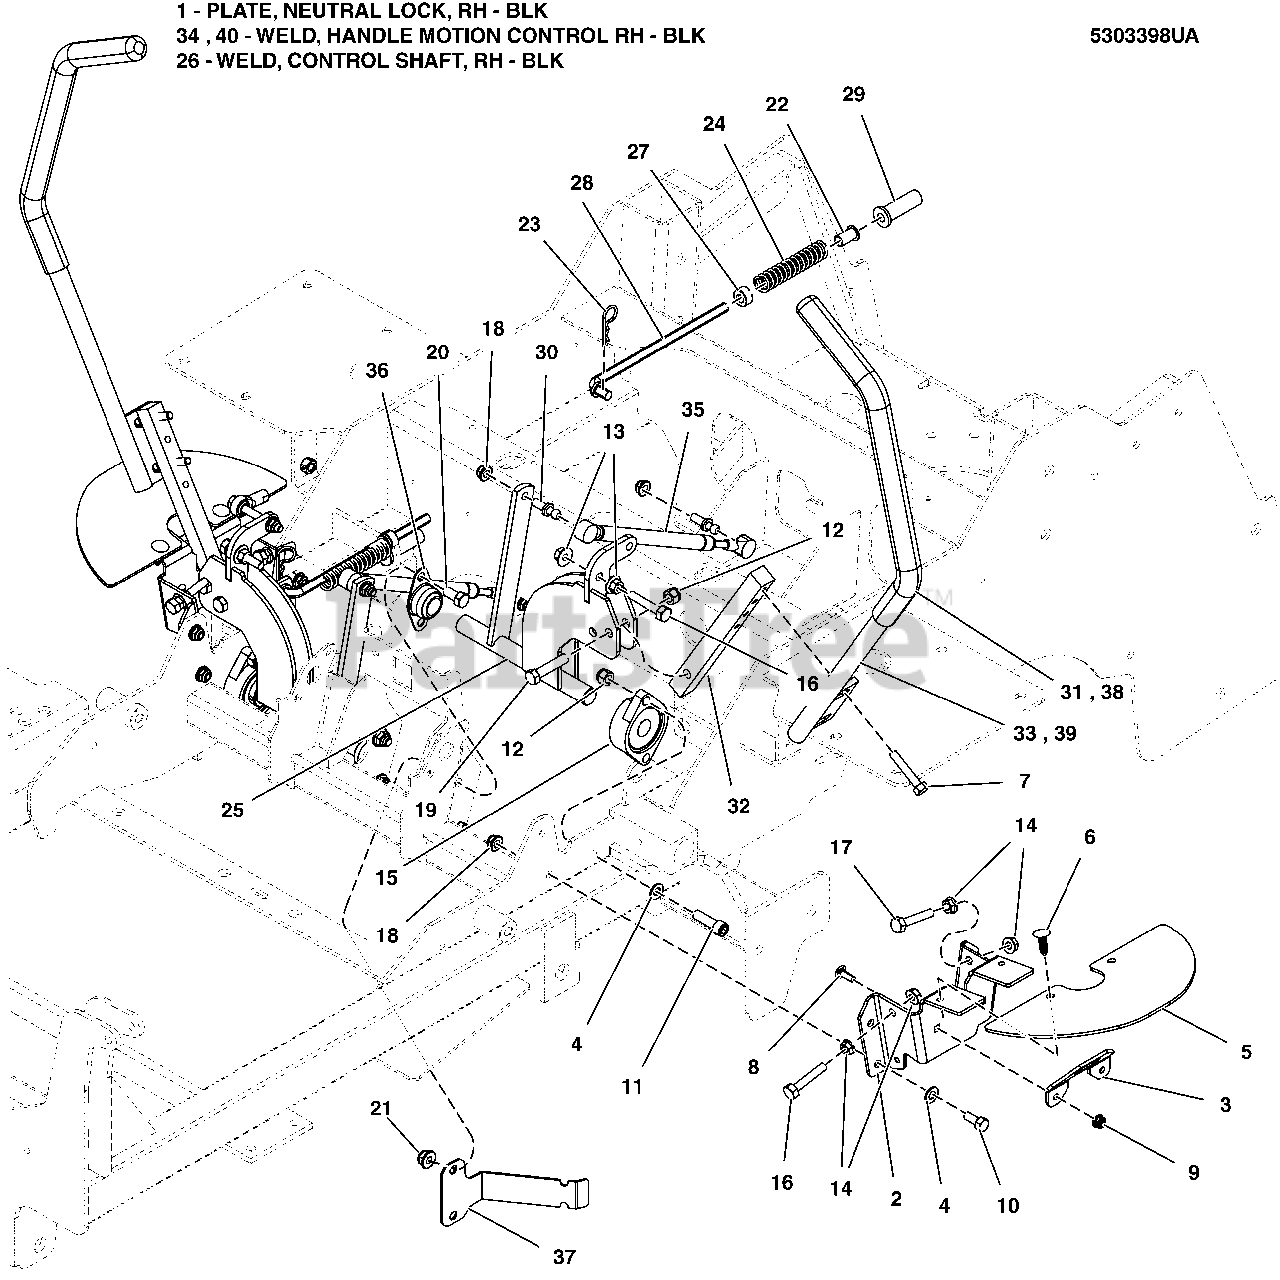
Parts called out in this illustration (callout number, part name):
1	PLATE, NEUTRAL LOCK, RH - BLK
2	PLATE, NEUTRAL LOCK, LH - BLK
3	BRACKET, SWITCH MOUNT - BLK
4	WASHER, 5/16
5	GUARD, RUBBER MOTION CONTROLS
6	PUSH RIVET (TREE TYPE), BLACK
7	CAPSCREW, Hex Head, Flange Whiz Lock, 5/16-18 x 3/4
8	BOLT, 1/4-20 x 3/4 Round Head Short Square Neck Carriage, GR 5, YZ
9	NUT, 1/4-20, GR5 Flanged Nylock, Zinc/Clear
10	CAPSCREW, Hex Head, 5/16-18 x 3/4
11	BOLT, 3/8-16 X 1-1/4 SHCS (SOCKET HEAD)
12	NUT, Hex, Nylon Lock, 3/8-16
13	NUT, 5/16-18 HEX SERRATED FLANGE (LARGE)
14	NUT, 5/16-18, Hex Serrated Flange (Small)
15	BEARING, FLANGE
16	BOLT, 5/16-18 X 1.25" GD 5 TFL
17	CAPSCREW, Hex Head, Flange Lock Taptite, 5/16-18 X 1-3/4
18	NUT, Ny Lock Flange, 5/16-18
19	CAPSCREW, Hex Head, 3/8-16 X 1-3/4
20	CAPSCREW, Hex Hd, 3/8-16 x 3/4 (S/N 616 & up)
21	NUT, 3/8-16, Hex Flange Nylock
22	BUSHING, FLANGE 3/8ID X 7/8 LONG
23	PIN, HAIR, .0915 X 1-7/8
24	SPRING, REVERSE RETURN
25	WELD, CONTROL SHAFT, LH - BLK
26	WELD, CONTROL SHAFT, RH - BLK
27	COLLAR, 3/8" SET
28	ROD, NEUTRAL RETURN, CZ
29	FLANGED BUSHING, 3/8IDX.63ODX.8125FL
30	10MM BALL STUD, 5/16-18 X 3/4 THDS
31	GRIP, FOAM, 3/4" ID, 16" LONG
32	MOUNT, CONTROL ARM - BLK
33	WELD, HANDLE MOTION CONTROL LH - BLK
34	WELD, HANDLE MOTION CONTROL RH - BLK
35	DAMPENER, CONTROL, #(P6709/P3610)
36	BEARING, Flange, Bronze, 3/4"
37	BRACKET, HARNESS MOUNT, 2100 - BLK
38	GRIP, FOAM, 1" ID, 16" LONG
39	WELD,HANDLE MOTION CNTRL,19.0,1.0,LH,BLK
40	WELD,HANDLE MOTION CNTRL,19.0,1.0,RH,BLK
